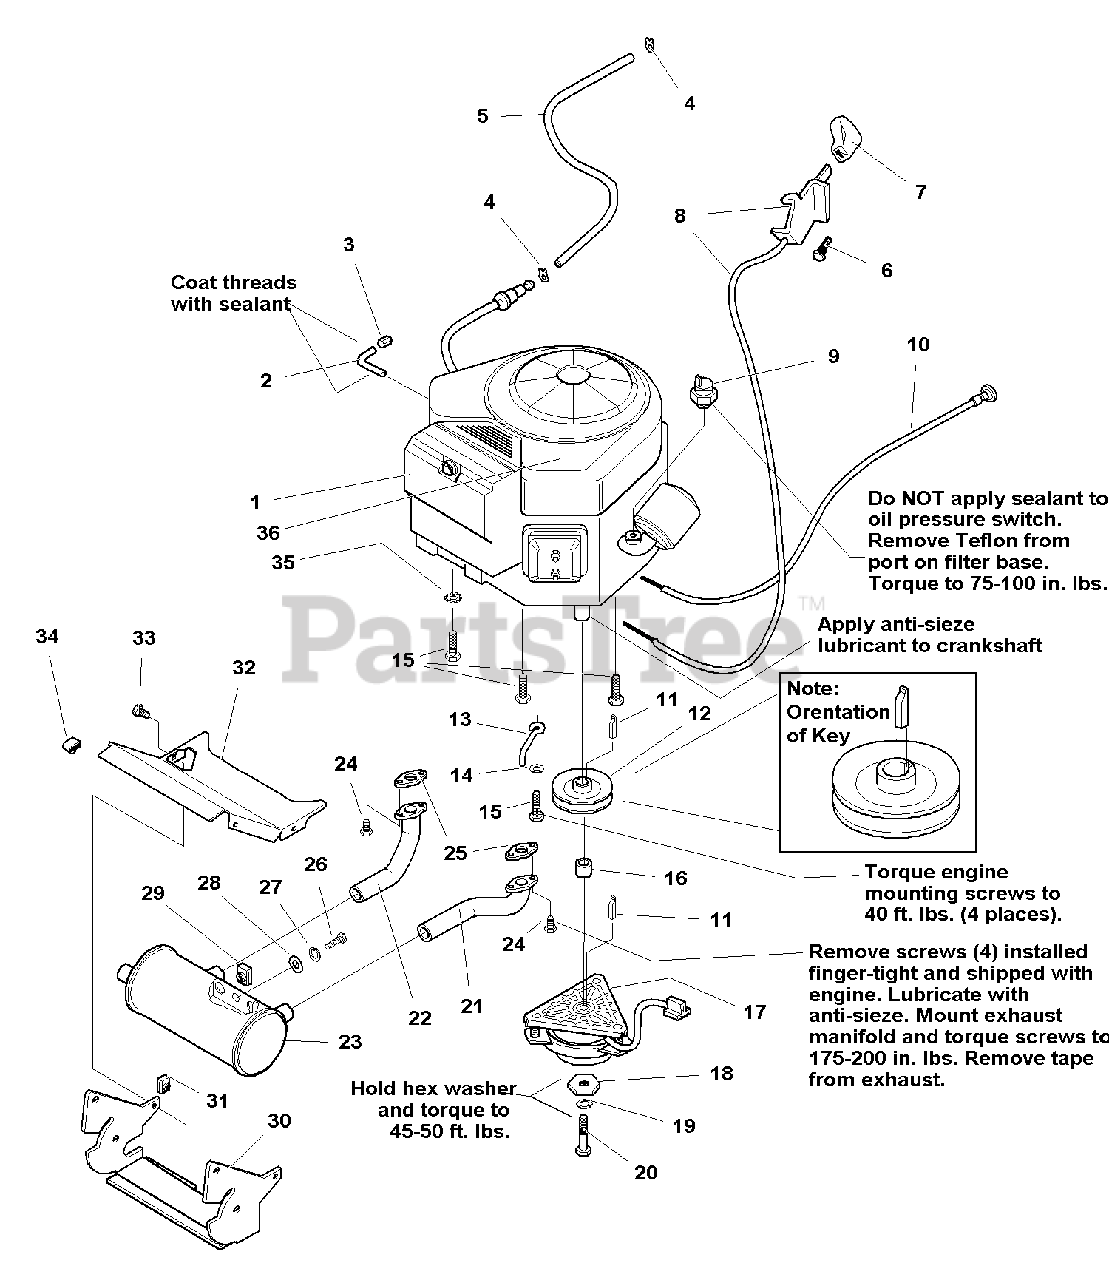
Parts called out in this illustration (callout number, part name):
1	ENGINE, 18HP Briggs & Stratton V-Twin
1	ENGINE, 20HP Briggs & Stratton V-Twin
2	DRAIN PIPE, Oil
4	CLAMP, Hose
5	HOSE, Fuel, 45.5"
6	CAPSCREW, Hex Head, Plastite, 1/4-20 x 1/2
7	KNOB, Throttle
8	THROTTLE CONTROL ASSEMBLY
9	SWITCH, Oil Pressure
10	CABLE, Choke Control
11	KEY, Hi-Pro
12	PULLEY ASSEMBLY
14	WASHER, 3/8
15	CAPSCREW, Hex Head, Taptite, 3/8-16 x 1-1/2
17	ELECTRIC CLUTCH ASSEMBLY, PTO
18	WASHER, Hex
19	WASHER, Lock, 7/16
20	CAPSCREW, Hex Head, 7/16-20 x 4
21	MANIFOLD PIPE, LH
22	MANIFOLD PIPE, RH
24	CAPSCREW, Hex Head, M8-1.25 x 20mm
25	GASKET
26	CAPSCREW, Hex Head, 5/16-18 X 1
27	WASHER, Lock, 5/16
28	WASHER, 5/16
29	NUT, Speed, 5/16-18
30	DUCT, Lower Exhaust
31	PAL NUT, 1/4-20
32	DUCT, Upper Exhaust
33	CAPSCREW, Hex Head, Whiz Lock, 1/4-20 x 5/8
34	CLIP
35	WASHER, Lock, External Tooth
36	DECAL, Engine (18HP Units Only)
